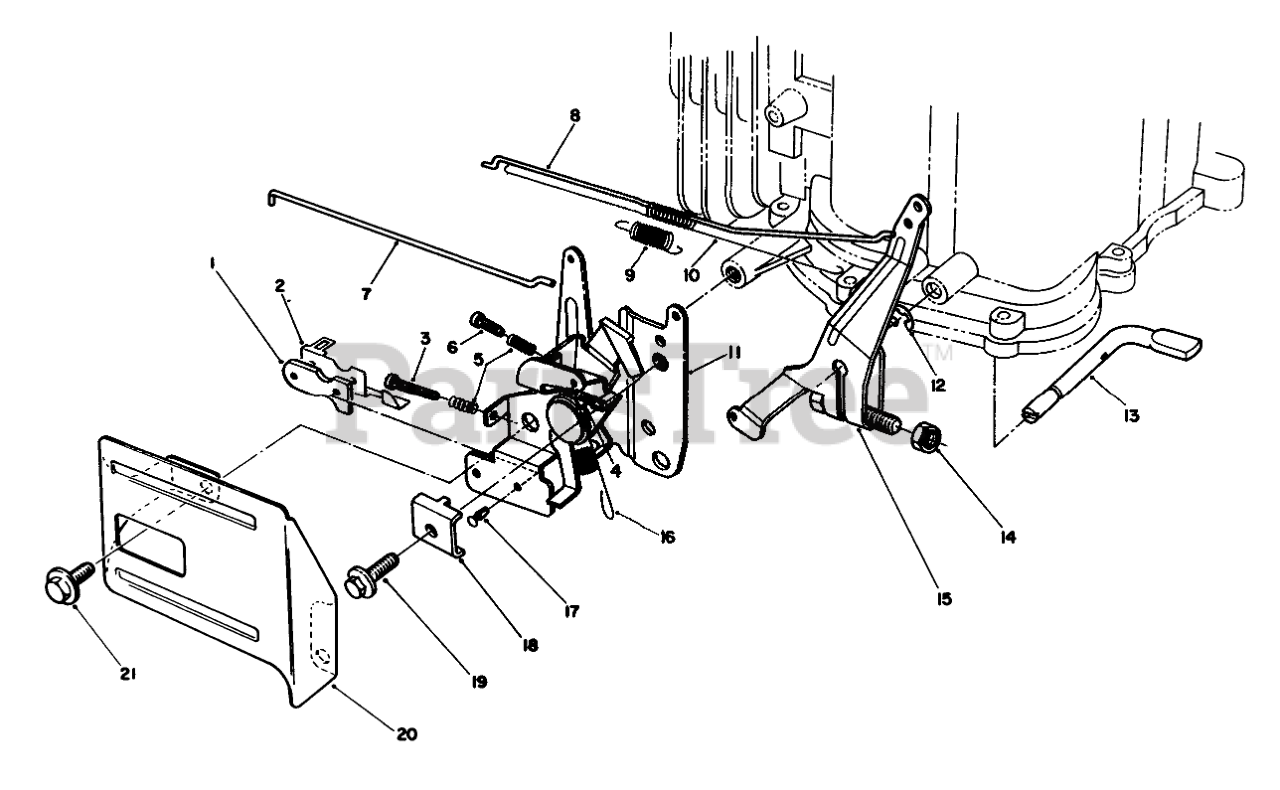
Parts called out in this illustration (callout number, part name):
1	INSULATOR-KILL SWITCH
2	TERMINAL-KILL SWITCH
3	SCREW
4	SPRING
5	SPRING
6	SCREW
7	Rod-Choke
8	Rod-Carburetor
9	SPRING
10	SPRING
11	THROTTLE
12	E-RING
13	SHAFT
14	Nut
15	ARM ASM
16	SPRING
17	RIVET
18	CLAMP-CABLE
20	THROTTLE GUARD
